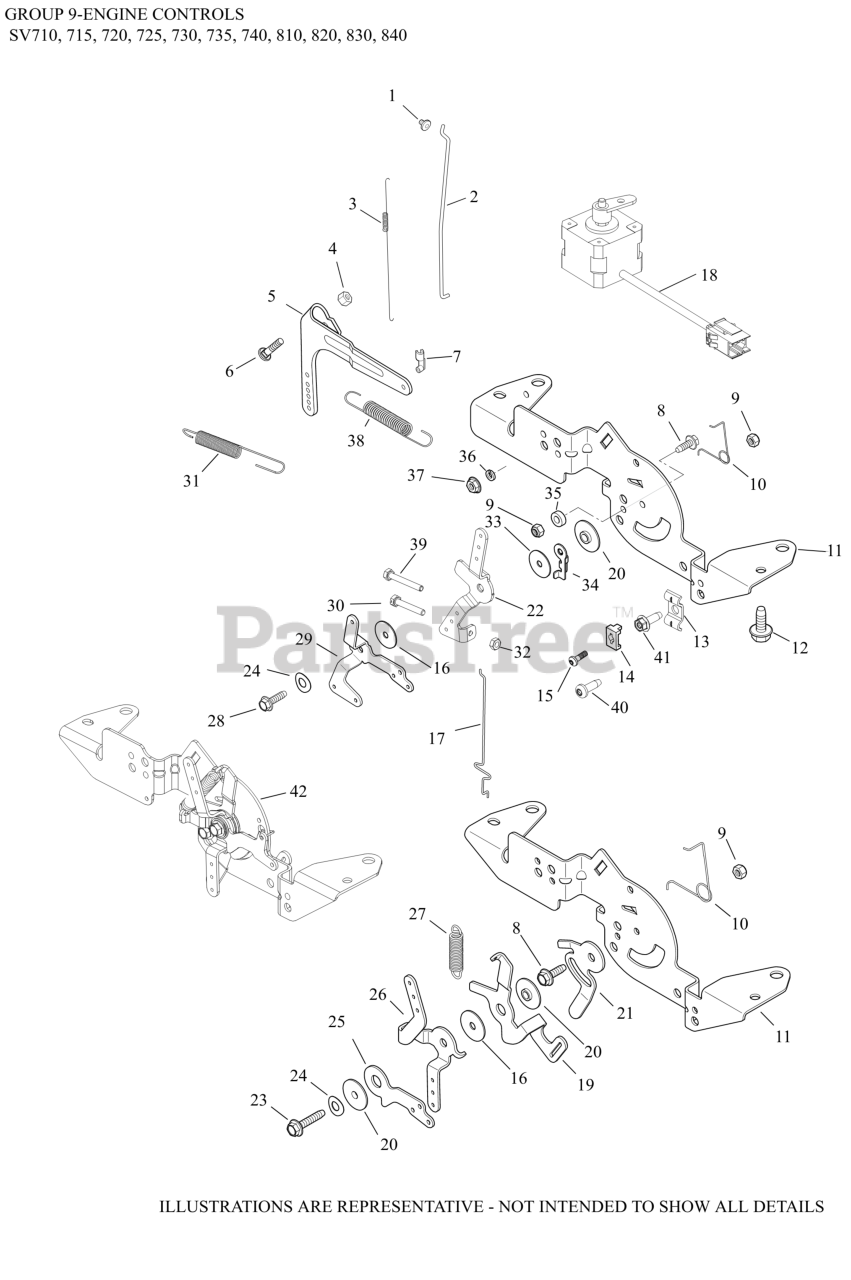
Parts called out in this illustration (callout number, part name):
1	BUSHING, LINKAGE RETAINING
2	LINKAGE, THROTTLE
3	SPRING, LINKAGE
4	NUT, FLG M6X1.0
5	LEVER, GOVERNOR - (#2409069S)
6	BOLT, RD HD SQ NECK M6X1.0X25
7	BUSHING, THROTTLE LINKAGE
9	SCREW, THREAD FORMING
9	NUT, LOCK M5X.8
10	SPRING, CHOKE RETURN
11	BRACKET, SPEED CONTROL
12	SCREW, THREAD FORMING
14	CLAMP, CABLE-(#2523753S)
16	WASHER, FLAT 5.5 MM
17	LINKAGE, CHOKE
20	SPACER, CONTROL ASSEMBLY
22	LEVER, THROTTLE CONTROL
24	WASHER, SPRING 1/4"
28	SCREW, THD FRM-USE 25 086 473-S
29	LEVER, CHOKE
30	SCREW, SLT HD CAP M4X0.7X25
31	SPRING, GOVERNOR
32	NUT, M4X0.7
33	WASHER, FLAT 5 MM
34	LEVER, THROTTLE ACTUATOR
38	SPRING, GOVERNED IDLE
NI	SCREW, THREAD FORMING
